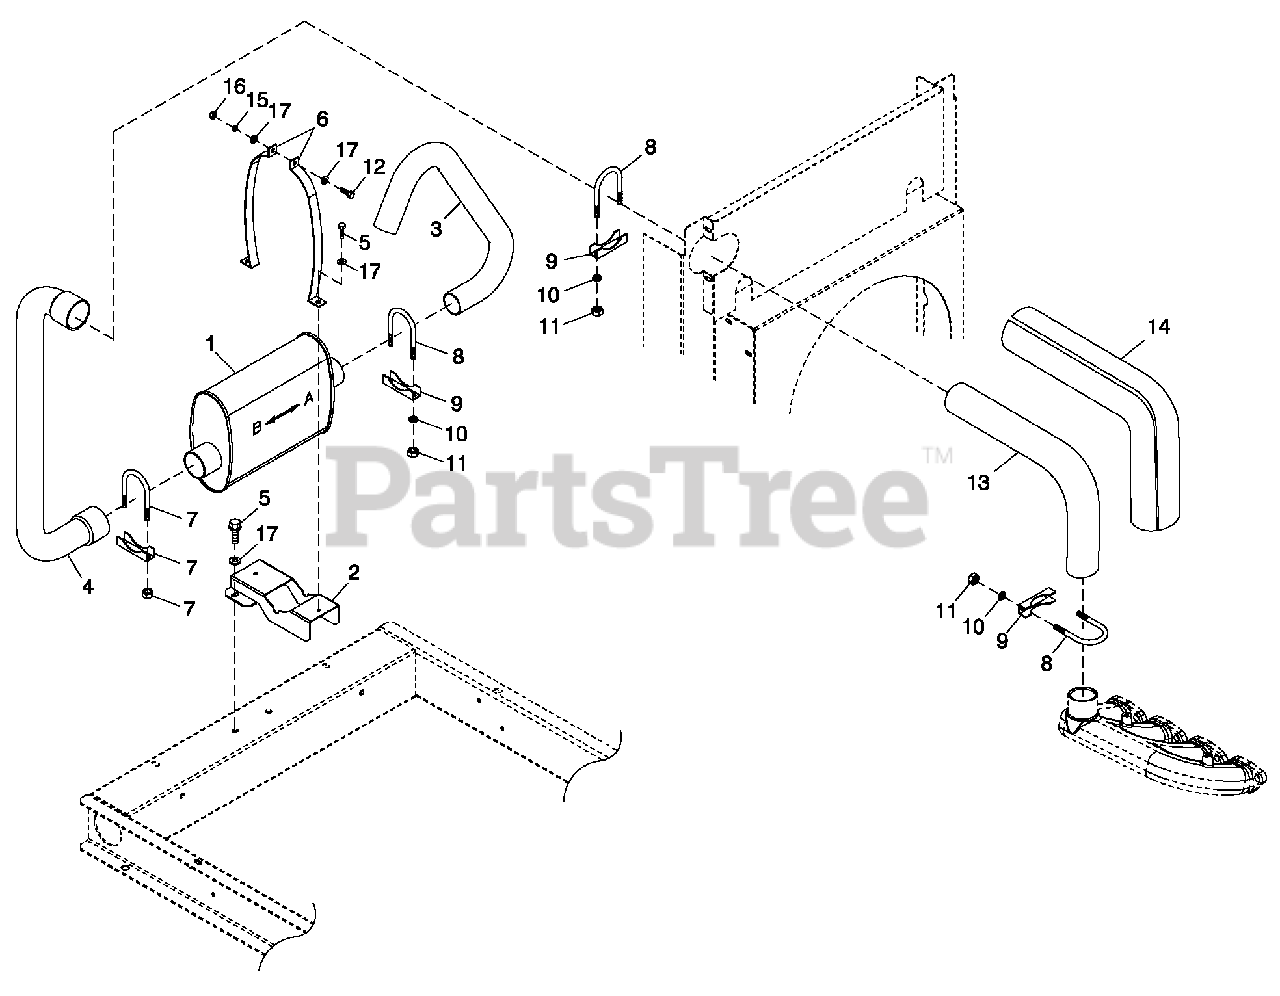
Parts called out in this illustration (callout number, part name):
1	MUFFLER C1
2	MUFFLER SADDLE
3	PIPE EXHAUST OUTLET
4	EXHAUST PIPE LOWER 1.6L
5	SCREW HWHTFM6-1.0X 16
6	MUFFLER STRAP
7	B OLTU 5/16-18X2-1/4
8	B OLTU 5/16-18X2.09
9	SADDLE 2 INCH
10	WASHER LOCK M8-5/16
11	NUT HEX 5/16-18 STEEL
12	SCREW HHC M6-1.0X 30 G8.8
13	EXHAUST PIPE UPPER 1.6L SS
14	EXHAUST B LANKET 500MM LONG
15	WASHER LOCK M6-1/4
16	NUT HEX M6 X 1.0 G8 YEL CHR
17	WASHER FLAT 1/4-M6 ZINC
